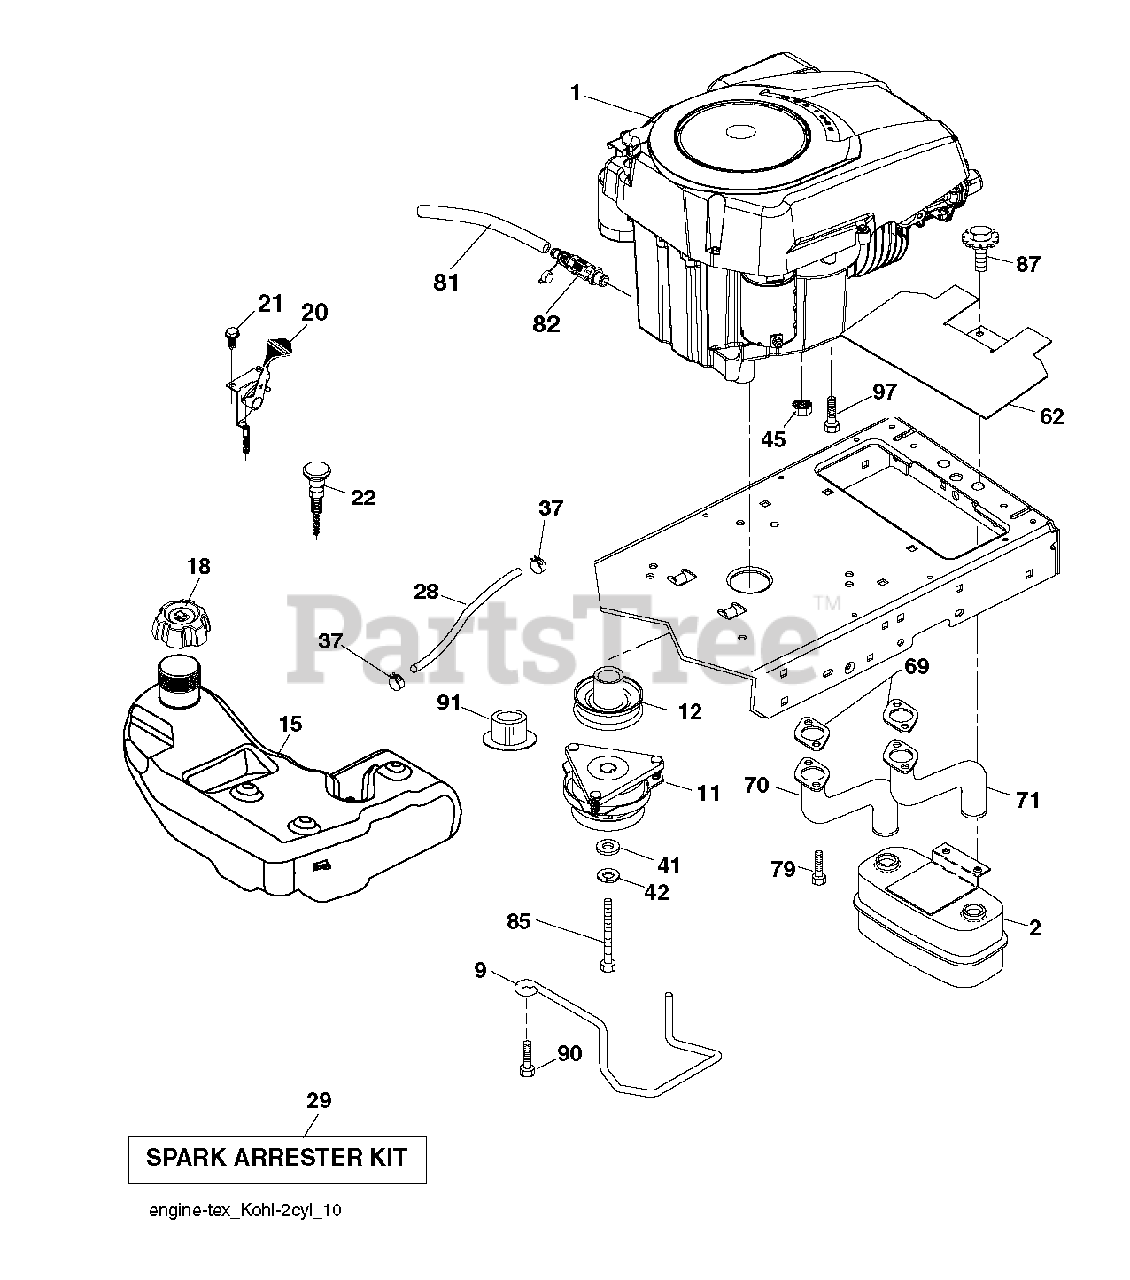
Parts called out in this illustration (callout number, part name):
2	MUFFLER.TWIN.CYL.LOW.TONE
9	KEEPER.BELT.ENGINE.4.2
11	CLUTCH.ELECTRIC.LT.48"*
12	PULLEY.ENGINE.TUFFTORQ
15	TANK.FUEL.SIDE-FILL.3.NON-EPA
18	RP CAP FUEL
20	THROTTLE CONTROL
21	SCREW.#10 X 0.750.BOS
22	CONTROL.CHOKE.ERGO.PUSH-IN.BLA
28	REPL BY 532 00 85-43
29	KIT.SPARK ARRESTOR 794945 B&S
37	HOSE CLAMP
42	LOCKWASHER
45	NUT
62	RP SHIELD HEAT MUFFLER
69	GASKET.EXHAUST.KOHL.CV18-CV26
70	RP.PIPE-EXHAUST LH
71	RP.PIPE-EXHAUST RH
79	SCREW.SOCKET HD.5/16-1
81	TUBE, DRAIN OIL ASM.
82	VALUE.OIL.DRAIN
85	BOLT HEX 7/16-20X4-1/4"
87	BOLT, 5/16-18 X 1 3/4
90	SCREW 3/8-16X1
91	BUSHING.1.375OD
97	SCREW 3/8-16X1
